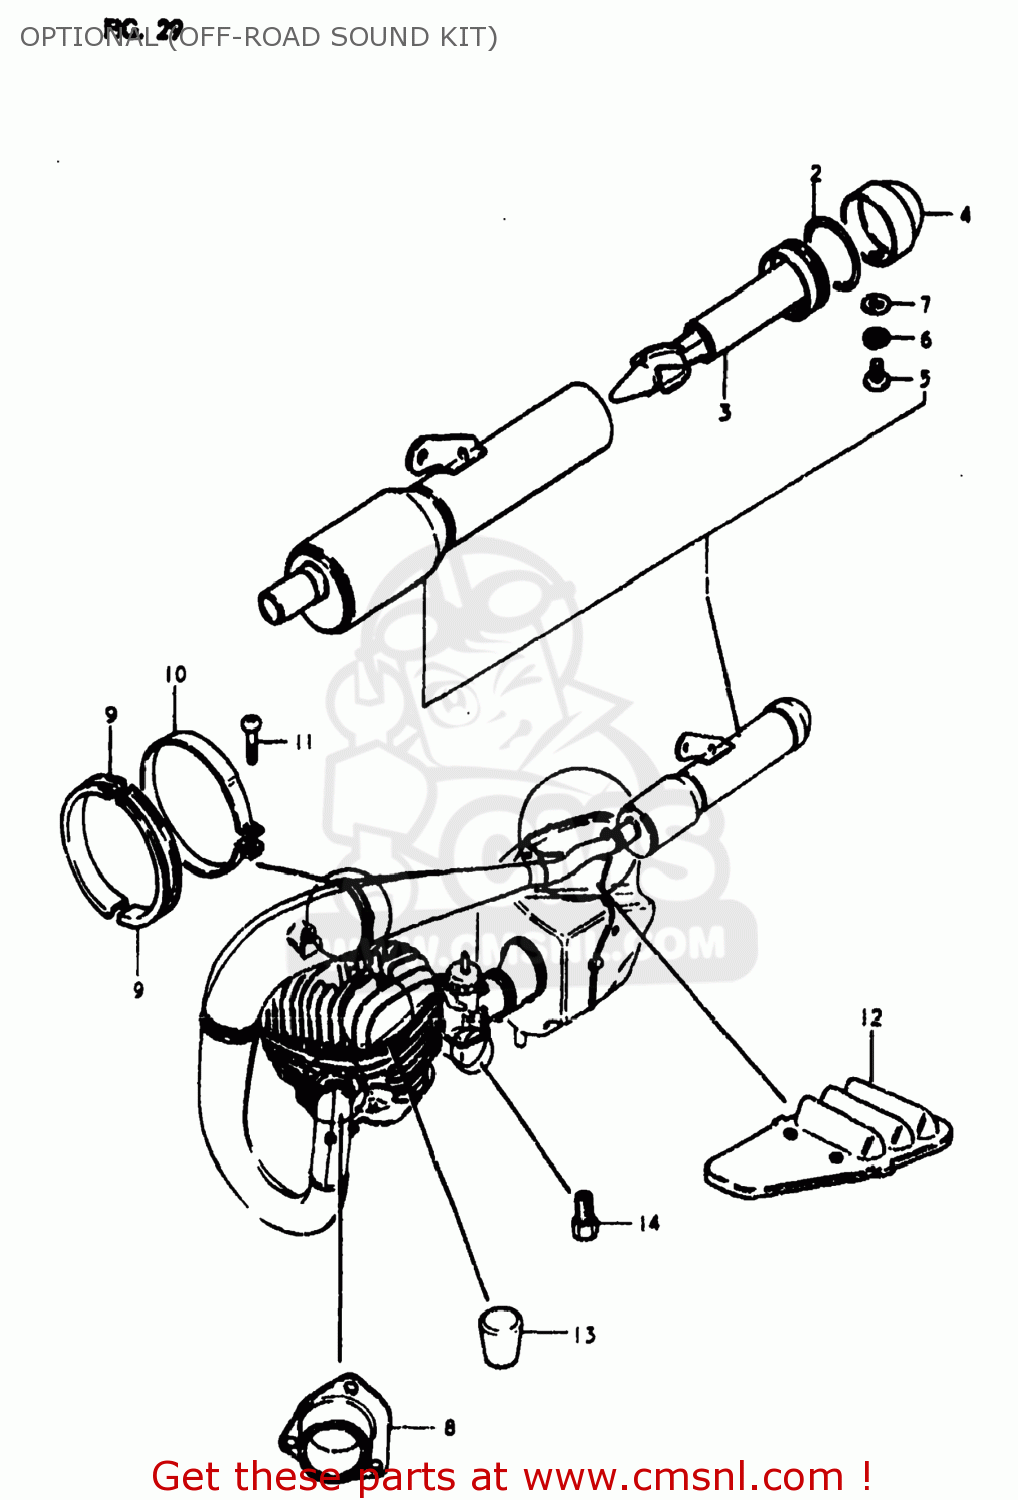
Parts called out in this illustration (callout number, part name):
1	MUFFLER ASSEMBLY
2	O-RING (D:3.5 ID:54.4)
3	TUBE,MUFFLER CLEAN OUT
4	COVER,SECOND MUFFLER TAIL
5	SCREW(6X8)
6	LOCK WASHER
7	WASHER
8	FLANGE,EXHAUST PIPE
9	BODY,MUFFLER
10	CLAMP
11	SCREW
12	CAP
13	PAD,CYLINDER HEAD
14	JET
